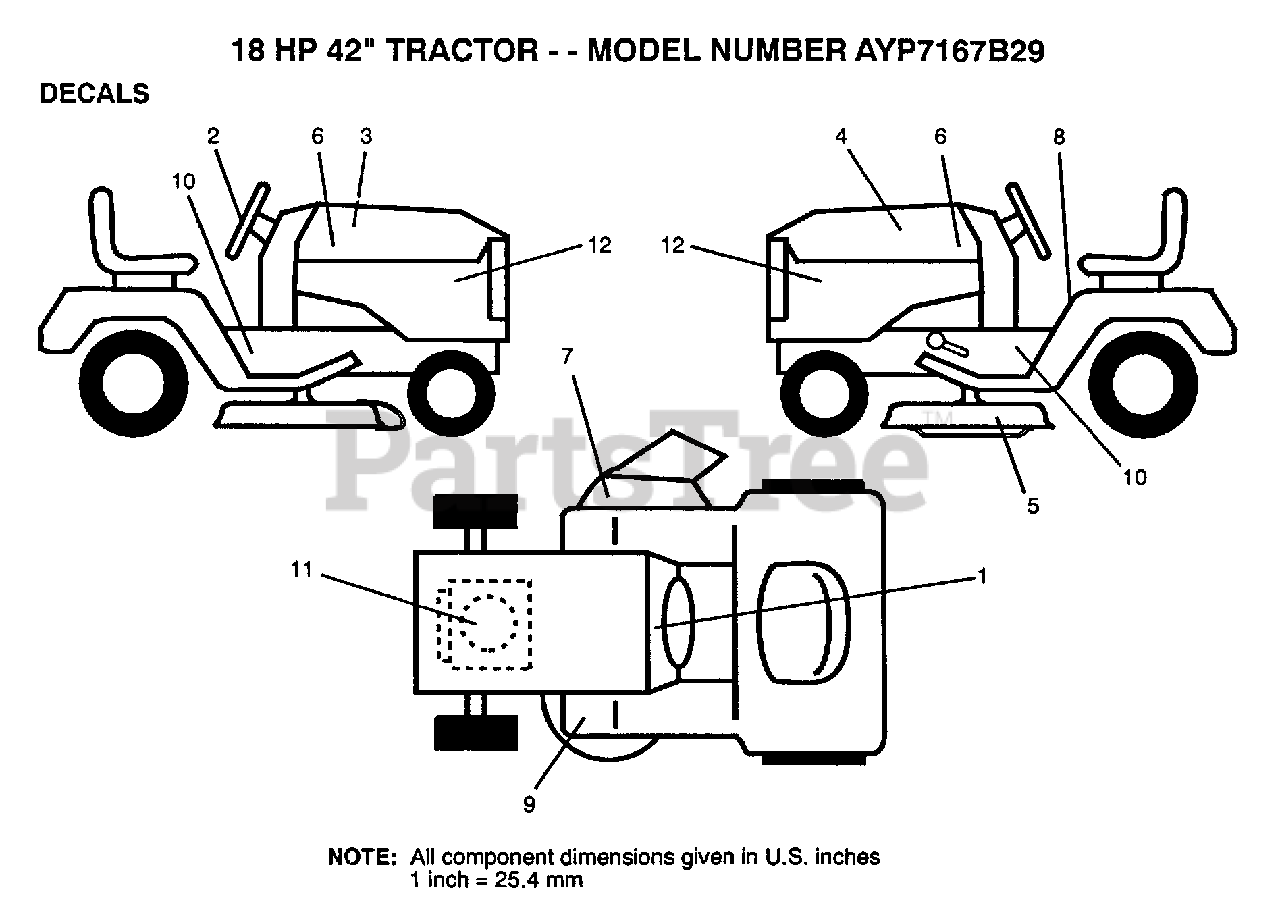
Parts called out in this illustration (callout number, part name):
5	DECAL INSTRUCTION CAUTION
7	DECAL WARING
8	DECAL
11	DECAL.ENG.805720
